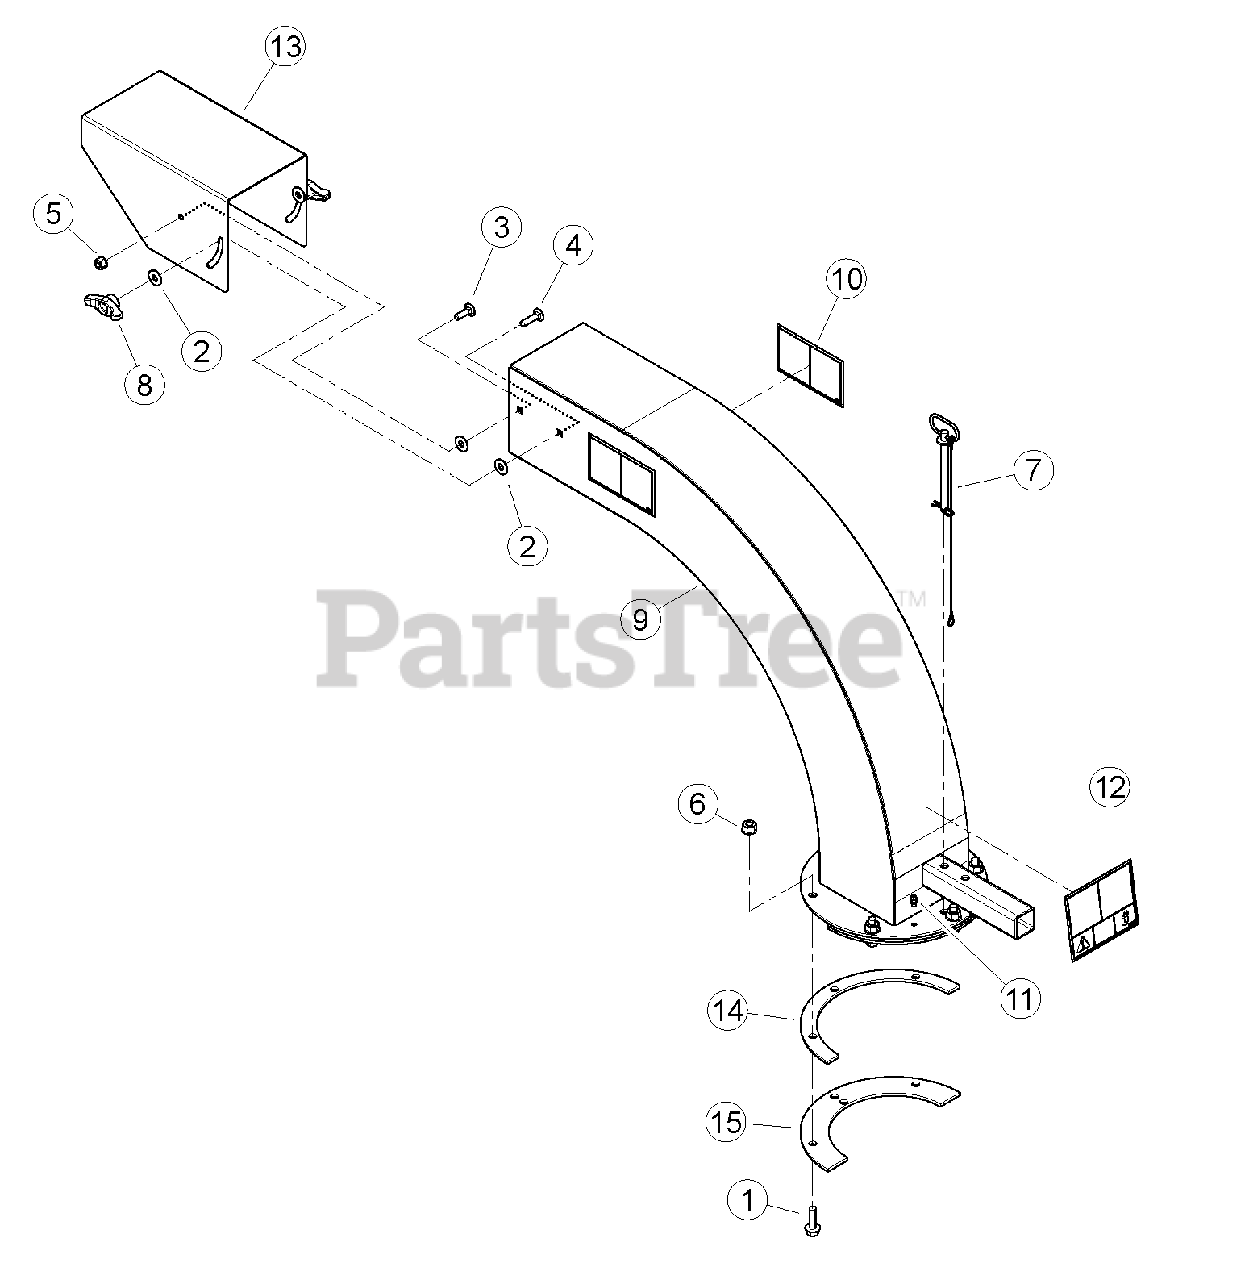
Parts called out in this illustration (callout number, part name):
1	BOLT, 3/8 X 1-1/4 FLANGE NC
2	WASHER, 5/16 FLAT ZP
3	BOLT, 5/16 X 1 GR5 CRG ZP
4	BOLT, 5/16 X 1-1/4 GR5 ZP CRG
5	NUT, 5/16-18 NYLOCK-FLANGE
6	NUT, 3/8-16 NYLOCK FLANGE
7	PIN, 3/8 X 4.25 DISCHARGE
8	KNOB, 5/16-18 UNC TEE W/LOCKING INSERT
9	ASSEMBLY, 6 INCH ORCHARD DISCHARGE CHUTE, SERVICE PART
10	DECAL, DISCHARGE ISO
11	FITTING, 1/4 SELF-TAP GREASE
12	DECAL, DISCHARGE DEBRIS & LOCK
13	CAP, 6 INCH ORCHARD DISCHARGE
14	SPACER, DISCHARGE PIVOT
15	RING, DISCHARGE CLAMP
